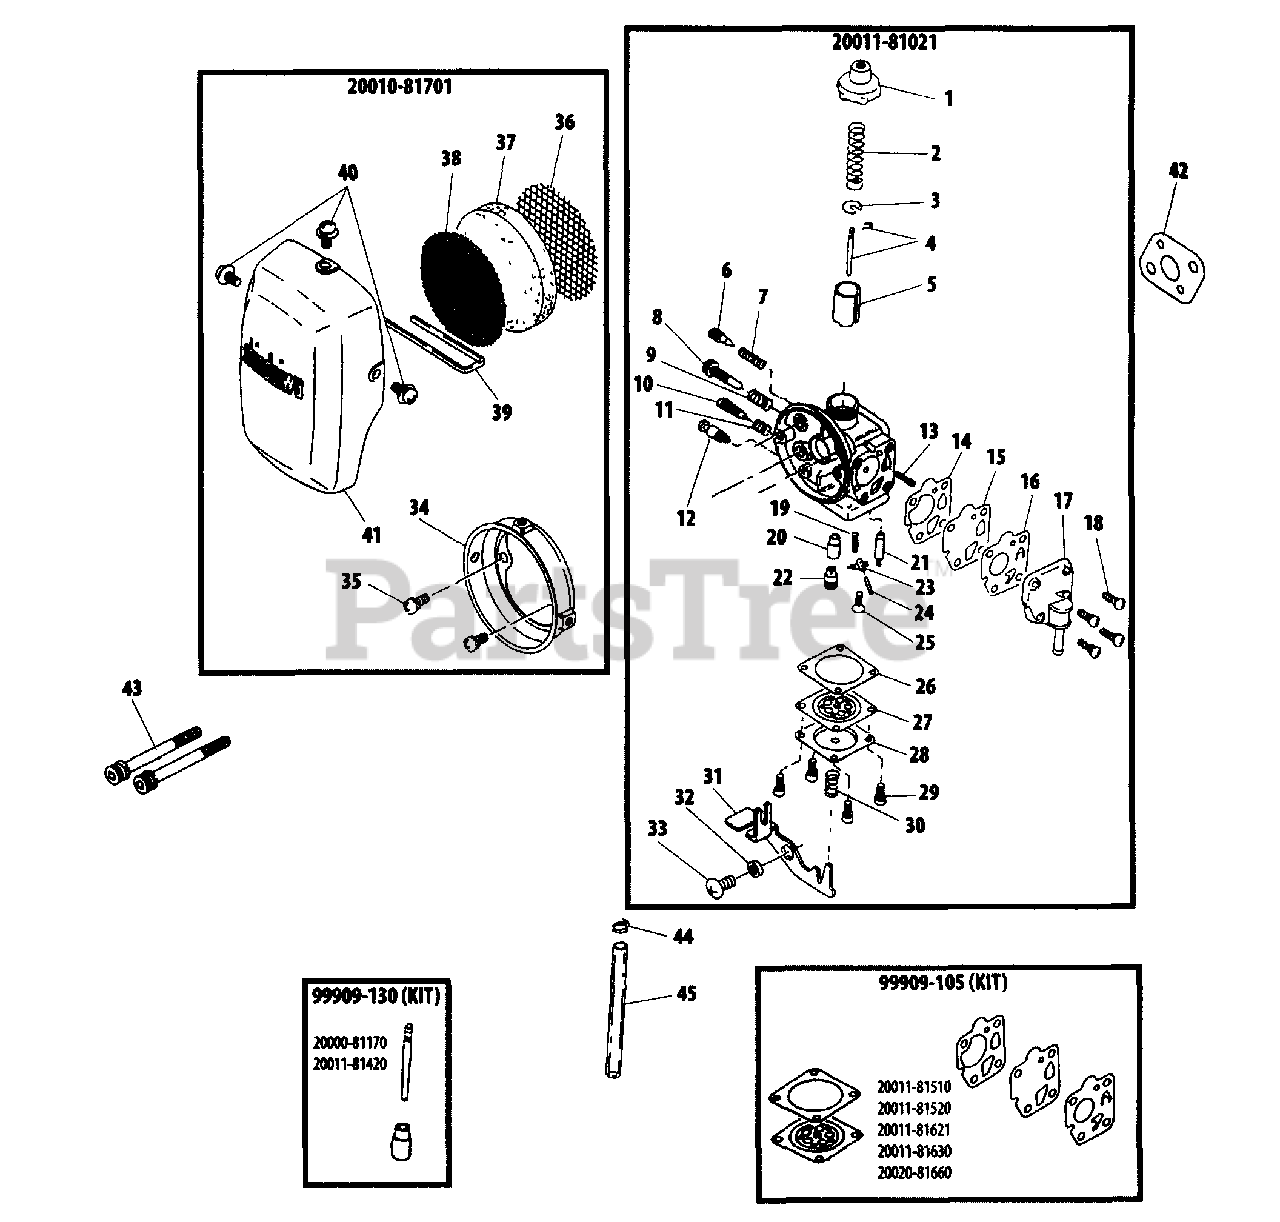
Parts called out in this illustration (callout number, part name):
1	CAP
2	SPRING
3	RETAINER
4	NEEDLE
5	VALVE, THROTTLE
6	SCREW, SLOW AIR
7	SPRING
8	SCREW, IDLE ADJUST
9	SPRING
10	SCREW, IDLE ADJUST
11	SCREW, IDLE ADJUST
12	VALVE, OVERFLOW
13	SPRING
14	GASKET, METERING
15	DIAPHRAGM, METERING
16	VALVE, PUMP
17	BODY, PUMP
18	SCREW
19	SPRING
20	HOLDER, JET
21	VALVE, INLET NEEDLE
22	JET
23	LEVER, METERING
24	PIN, METERING LEVER
25	SCREW, METERING LEVER PIN
26	GASKET
27	DIAPHRAGM, METERING
28	COVER, DIAPHRAGM
29	SCREW
30	SPRING
31	LEVER, TICKLER
32	COLLAR
33	SCREW
34	CASE, AIR FILTER
35	SCREW
36	SCREEN - INNER
37	FILTER, AIR - FOAM
38	SCREEN - OUTER
39	CLIP
40	SCREW
41	COVER, AIR FILTER
42	GASKET
43	SCREW - 5X50
44	CLIP
45	TUBE, OVERFLOW
20010-81701	AIR CLEANER ASSY
20011-81021	CARBURETOR
99909-105	DIAPHRAGM/GASKET KIT
99909-130	NEEDLE/JET KIT
